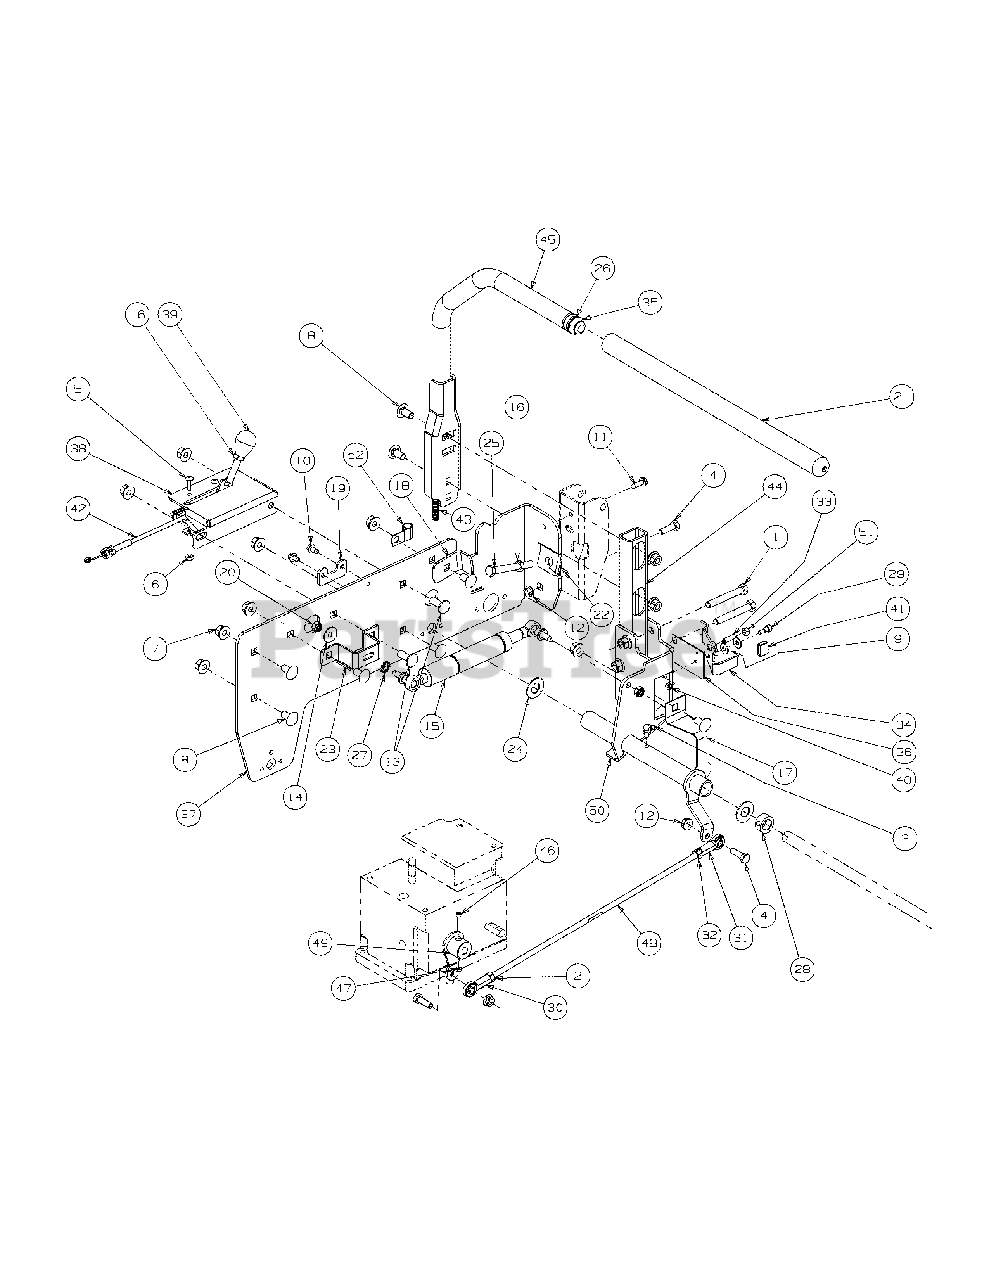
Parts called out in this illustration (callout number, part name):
1	HHCS, 3/8-16, 2.5
2	Hex Nut, 5/16-24
3	Grease Fitting, 90°, 1/4-28
4	HHCS, 5/16-18 x 1.0
5	Screw, Machine, 10-32 x 3/4
6	Nut, Lock, Nylon Insert, #10-32
7	Nut, Hex, Flange Lock, 3/8-16
8	Carriage Bolt, 3/8-16 x .75 Lg.
9	Flat Washer, 1/4"
10	Screw, TT, 1/4-20, 0.5, Hex Index Washer
11	Screw, TT, 1/4-20, 0.75, Hex Index Washer
12	Nut, Lock, HexFlange, 5/16-18
13	Carriage Bolt, 3/8-16 x 1
14	Belle Washer, .325 x .930 x .045
15	Cylinder Return to Neutral Kit
16	Nut, 3/8-16, Jam
17	Lever, Safety Switch
19	Holder Shaft, Park Brake
20	Nut, Hex, Center Lock, M8
21	Grip, 1.0
22	U-Nut, 3/8-16, .75
23	Bracket Assembly, Mount Dampener
24	Flat Washer, 5/8 Nylon
25	HHCS, 3/8-16, 3.00
26	Lock Washer, Ignition Switch
27	External Tooth Washer, 3/8
28	Shaft Collar
29	Shoulder Bolt, 1/4x1/4
30	Rod End, 5/16, Right Hand
31	Rod End, 5/16, Left Hand
32	Hex Nut, 5/16-24, Left Hand
33	Plunger, 1/4-20 x 3/4
34	Speed Control Adjuster Assembly, LH
35	Lapbar Switch, On/Off
36	Speed Control Detent Plate
37	Control Panel Mount, LH
38	Deflector Control Mounting Plate
39	Transmission Lever Knob
40	Nut, 10-24, w/Star Washer
41	Grip, Speed Lever
42	Remote Deflector Cable
43	Split Conduit, 1/4" Poly
44	Mounting Handle
45	Lapbar Switch Handle Assembly, LH
46	Sockethead Capscrew,, M4 x 0.7 x 25mm
47	Nut, M4 x 0.7mm, Nylock
48	Control Rod, 5/16-24, RH/LH x 16.5
49	Pump Mount Bracket
50	Hub Assy, Control LH Bearing
51	Nut, 1/4-20, Hex
52	Heat Shield Clip
